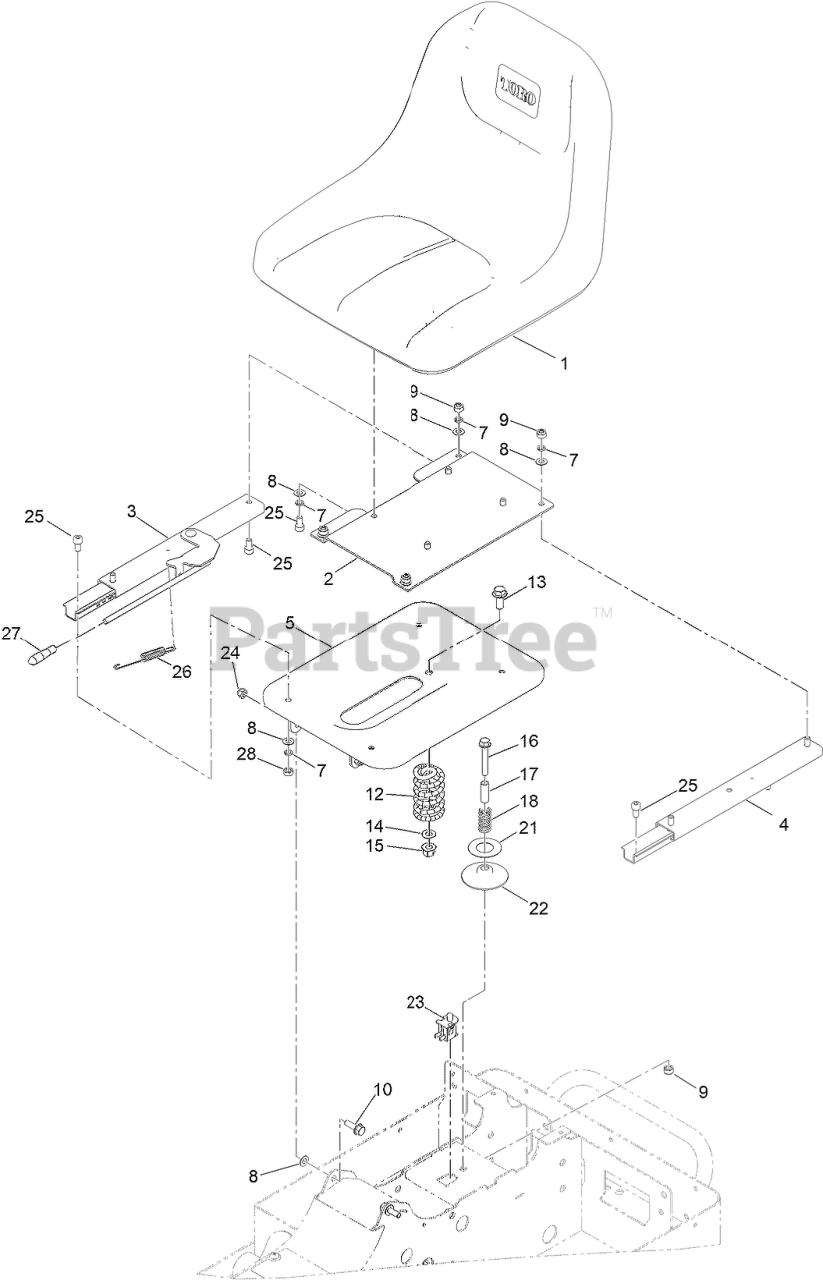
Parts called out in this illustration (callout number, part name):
2	MOUNTING PLATE, SEAT
3	SEAT SLIDE ASM, RH
4	SEAT SLIDE ASM, LH
5	SEAT BASE, ASM
7	WASHER-SPRING
8	WASHER-PLAIN
9	NUT-HEX, NI
10	SCREW-HHF
12	SPRING, SEAT
13	SCREW-HHF
14	WASHER-PLAIN
15	NUT-FLANGE, NI
16	SCREW-HHF
17	SHAFT, SPRING
18	SMALL SPRING, SEAT
21	WASHER
22	PLATE, SPRING SEAT
23	SEAT SENSOR
24	NUT, SEAT
25	BOLT SEAT, SLIDE MOUNT
26	ADJUSTMENT SPRING, SEAT
27	ADJUSTMENT LEVER CAP, SEAT
28	NUT-HEX
